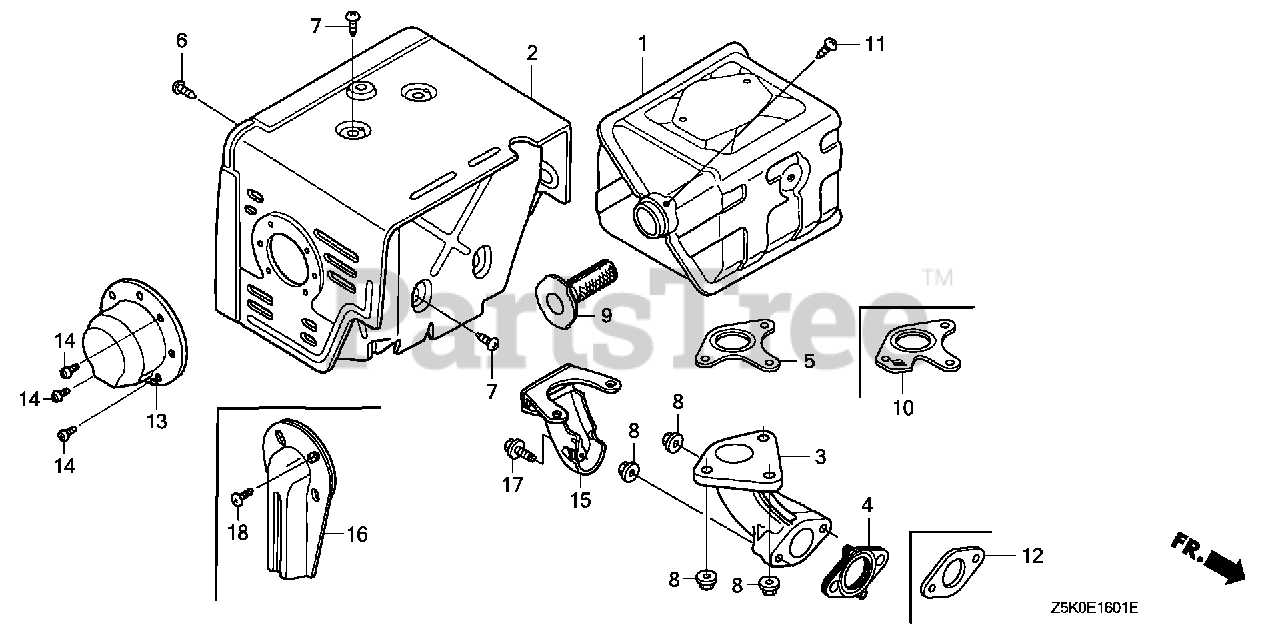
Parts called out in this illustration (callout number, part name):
1	MUFFLER (100DB)
2	PROTECTOR, MUFFLER
4	GASKET, EX. PIPE
5	GASKET, MUFFLER (NIPPON LEAKLESS)
5	GASKET, MUFFLER (THAI LEAKLESS)
6	SCREW, TAPPING (6X10)
7	SCREW, TAPPING (5X8)
8	NUT, FLANGE (8MM)
